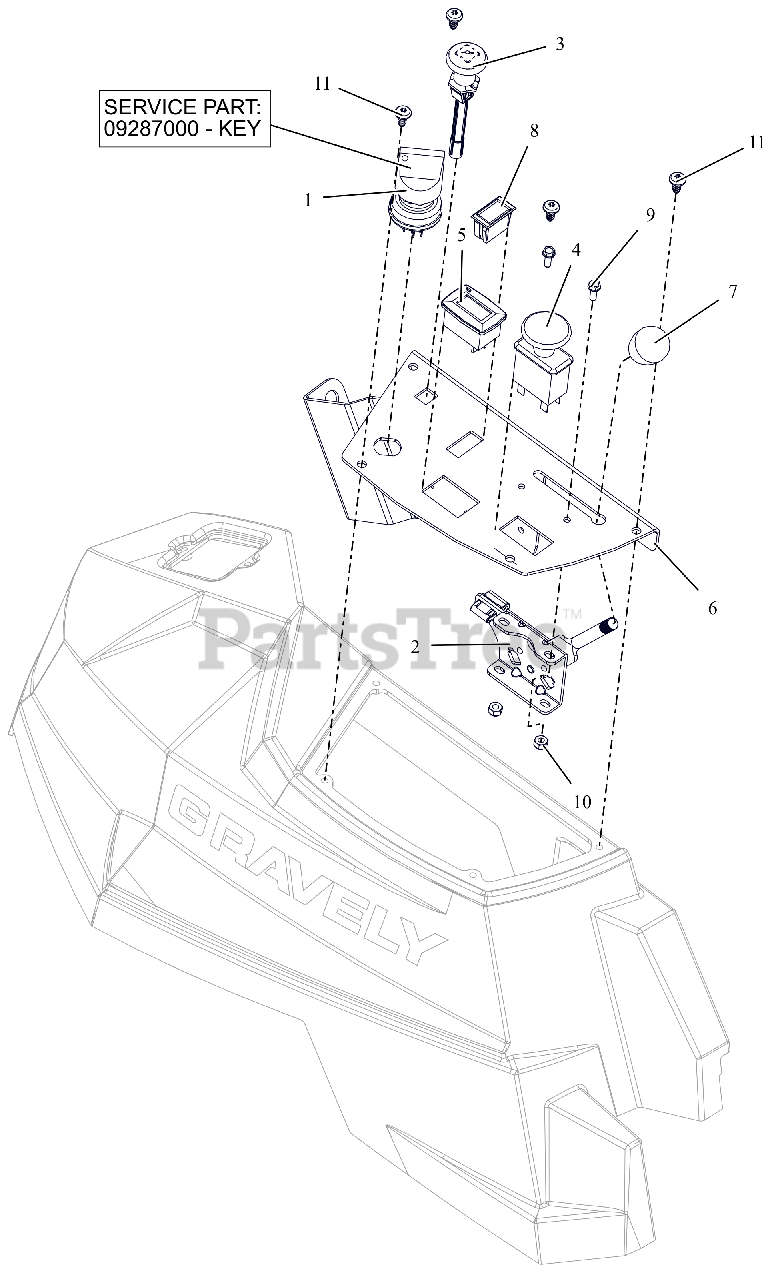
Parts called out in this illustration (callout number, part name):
1	SWITCH, IGNITION
1	KEY, W/ SHIELD
2	CABLE, PRO THROTTLE CONTROL
3	CABLE - CHOKE, SNAP-IN
4	SWITCH, CLUTCH
5	METER, HOUR W/MAINTENANCE
6	PANEL, HD CONTROL
7	KNOB-CONTROL-BLACK .38-16X.50
8	SWITCH,BLANK
9	BLT, HWH #10-24X.50 ZCC
10	NUT-LK-NYL #10-24 G2 ZCC
11	SCR-PAN .25-15X.50 6L H/LZB500
